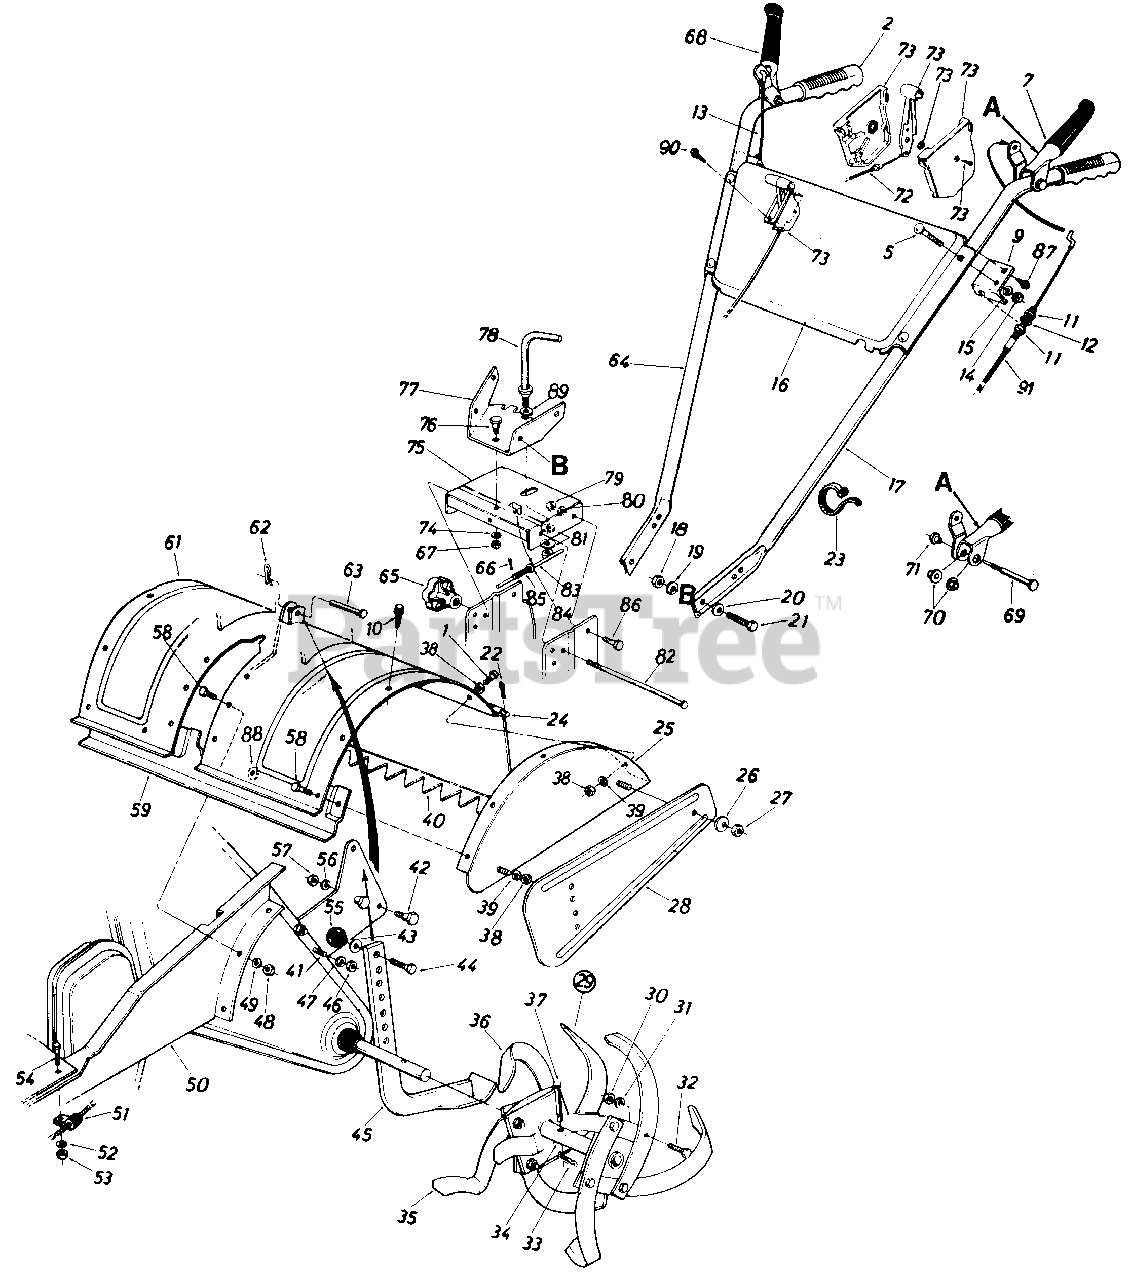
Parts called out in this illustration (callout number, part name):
1	Hex Bolt 5/16-18 x 11/4" Lg.
5	Carr. Bolt 5/16-18 x 1.75"*
7	Clutch Grip Ass'y.-L.H. (Tines)
9	Clutch Cable Bracket
10	Hex Wash. S-Tap Scr. 5/16-18 x .62" Lg.
11	Hex Nut 5/16-24 Thd.
12	L-Wash. 5/16" I.D.
13	Wheel Drive Cable
14	Hex Nut 5/16-18 Thd.
15	L-Wash. 5/16" I.D.
16	Handle Panel
17	Handle-L.H.
18	Hex Nut 3/8-16 Thd.
19	L-Wash. 3/8" I.D.*
20	Bell-Wash. 3/8" I.D.
21	Hex Bolt 3/8-16 x 1.00" Lg.
22	Cotter Pin 3/32" Dia. x 3/4"*
23	Cable Tie
24	Tiller Flap Rod
27	Hex Nut 5/16-18 Thd.
31	L-Wash. 3/8" I.D.
32	Hex Bolt 3/8-24 x 1.25" Lg.
33	Hairpin Cotter
38	Hex Nut 5/16-18 Thd.
39	L-Wash. 5/16" I.D.
41	Hex Bolt 5/16-18 x 1.0" Lg.
42	Shld. Bolt 1/2" Dia. x .426"
43	Fl-Wash. 3/8" I.D. x 5/8" O.D.
44	Hex Bolt 3/8-16 x 3/4" Lg.
45	Depth Bar Ass'y.
46	Hex Nut 5/16-18 Thd.
47	L-Wash. 5/16" I.D.*
48	Hex Nut 5/16-18 Thd.
49	L-Wash. 5/16" I.D.
52	L-Wash. 5/16" I.D.
53	Hex Nut 5/16-18 Thd.
54	Hex Bolt 5/16-18 x 3/4" Lg.
55	Ball Knob 11/4" Dia.
56	L-Wash. 3/8" I.D.
57	Hex Nut 3/8-16 Thd.
58	Hex Bolt 5/16-18 x .75" Lg.
63	Clevis Pin 3/8" Dia.
64	Handle-R.H.
65	Hand Knob
66	Cotter Pin 1/16" Dia. x .75" Lg.
67	Hex Cent. L-Nut 3/8-16 Thd.
68	Clutch Grip Ass'y.-R.H. (Wheels)
69	Shoulder Bolt .38" Dia. x 1.53" Lg.
70	Hex Flange Plastic Bearing
71	Shoulder Nut 1/4-20 Thd.
72	ThroKle Control Wire
73	Throttle Control Box Ass'y.
74	Bell-Wash. .40" I.D.
79	Hex Cent. L-Nut 3/8-16 Thd.
80	Bell-Wash. .40" I.D. x .88" O.D.
81	Bell-Wash. 1/2" I.D. x 1.00" O.D.
82	Lock Pin 5/16" Dia. x 8"
83	Lower Sliding Ass'y.
84	Fl-Wash. .291" I.D. x .62" O.D.
85	Compression Spring .36" O.D. x 1.00" Lg.
86	Shoulder Bolt 1/2" Dia. x .170" Lg.
87	Hex Wash. S-Tap Scr. 1/4-20 x.50" Lg.
88	Bell-Wash. 5/16" I.D.
89	Fl-Wash. 5/8" I.D.
90	Self-Tap Scr. #10 x 1/2" Lg.
91	Tine Control Cable
